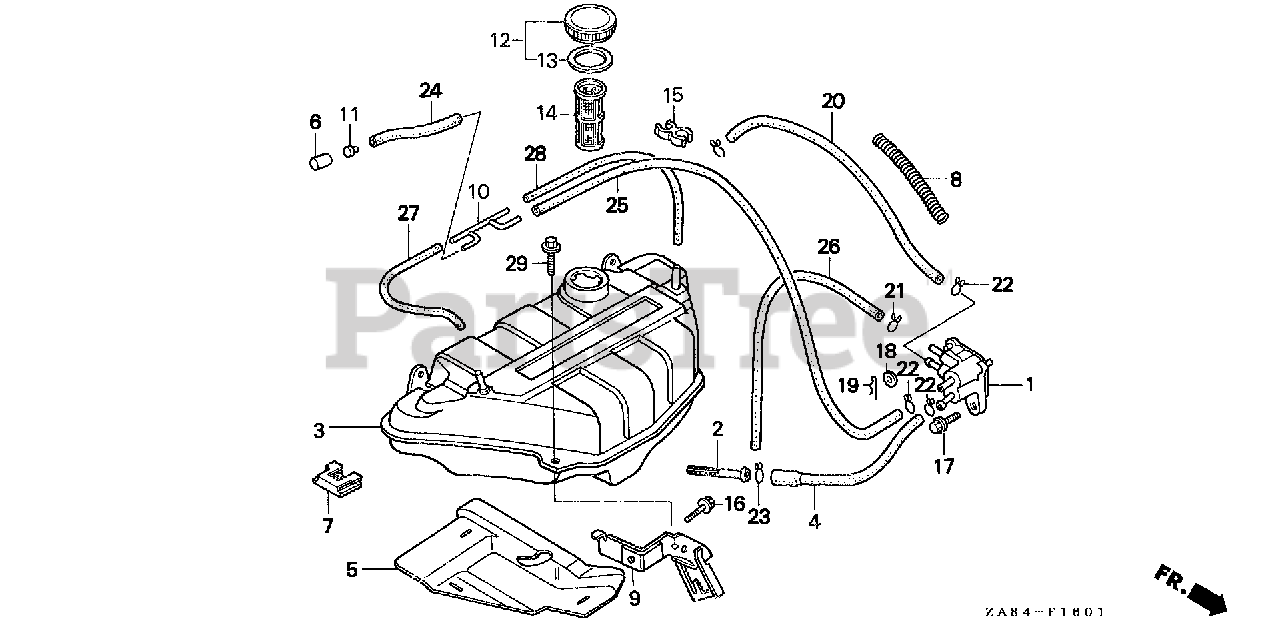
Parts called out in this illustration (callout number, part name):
1	PETCOCK ASSY.
2	FILTER, FUEL
3	TANK, FUEL
4	TUBE, FUEL TANK
5	SEPARATOR, TANK (LOWER)
6	ELEMENT, HANDLE BREATHER
7	RUBBER, TANK MOUNTING CENTER
8	SPRING, FUEL TUBE COVER
9	STAY, TANK
10	JOINT, BREATHER TUBE
11	FILTER, GASOLINE
12	CAP, FUEL FILLER
13	GASKET, FUEL FILLER CAP
14	FILTER, FUEL
15	CLAMP, IGNITION WIRE
16	BOLT, FLANGE (5X12)
17	BOLT, FLANGE (6X12) (CT200)
18	WASHER, PLAIN (6MM)
19	PIN, LOCK (6MM)
20	BULK HOSE, FUEL (4.5X3000) (4.5X230)
21	CLIP, TUBE (B7)
22	CLIP, TUBE (B8)
23	CLIP, TUBE (C11)
24	BULK HOSE, VACUUM (3.5X1000) (3.5X55)
25	BULK HOSE, VACUUM (3.5X1000) (3.5X315)
26	BULK HOSE, VACUUM (3.5X1000) (3.5X380)
27	BULK HOSE, VACUUM (4.5X1000) (4.5X135)
28	BULK HOSE, VACUUM (4.5X1000) (4.5X160)
29	BOLT, FLANGE (5X10)
